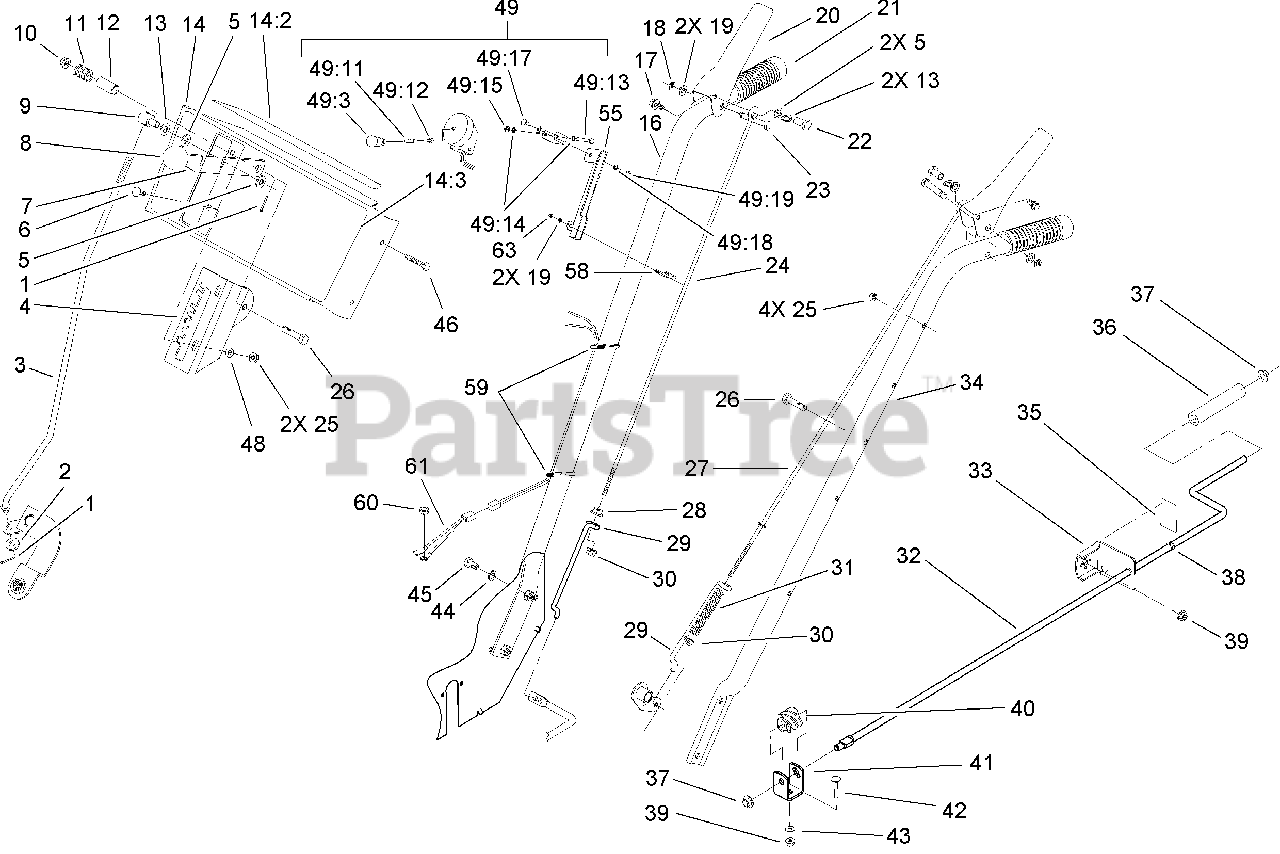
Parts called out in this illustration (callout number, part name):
1	PIN-COTTER
2	WASHER-FLAT
3	ROD-SHIFT
4	MOUNT-SPEED SELECTOR
5	WASHER-FLAT
6	SCREW-CARR
7	SELECTOR-SPEED
9	TRUNNION
13	WASHER-SPRING
14	Control Panel ASM
14:2	Decal-Escutcheon, Back
14:3	Decal-Panel, Control
16	HANDLE-RIGHT
17	SCREW-HHF
18	RING-CLIP
19	WASHER-FLAT
20	HANDLE-CONTROL
21	GRIP-HANDLE
22	POST-MOUNTING, LINKAGE
23	PIN-LEVER, CONTROL
24	ROD-UPPER ENGAGE AUGER
25	NUT-LOCK, NI
26	SCREW-HH
27	ROD-UPPER TRACTION
29	ROD-LOWER TRACTION
32	ROD-CONTROL, CHUTE
33	BRACKET-ROD, CHUTE
34	LEFT HANDLE
35	DECAL-CHUTE DIRECTION
36	GRIP-CONTROL, CHUTE
37	RETAINER-PUSH ON
38	Bushing
39	NUT-LOCK, NI
40	GEAR-WORM, CHUTE
41	BRACKET-WORM
42	SCREW-CARR
43	WASHER-LOCK
44	WASHER-BELLEVILLE
45	SCREW-HWH
46	SCREW-HH
48	WASHER-FLAT
49	HEADLAMP ASM
49:3	BEAM-SEALED
49:11	SWITCH ASM
49:12	BOOT-SWITCH
49:13	SCREW-HH
49:14	WASHER-LOCK
49:15	LOCKNUT-FLANGE
49:17	SCREW-CARR
49:18	WASHER-LOCK
49:19	NUT-HEX
55	LIGHT MOUNT ASM
59	TIE-CABLE
60	NUT-HEX
61	WIRE ASM
63	NUT-LOCK, NI
